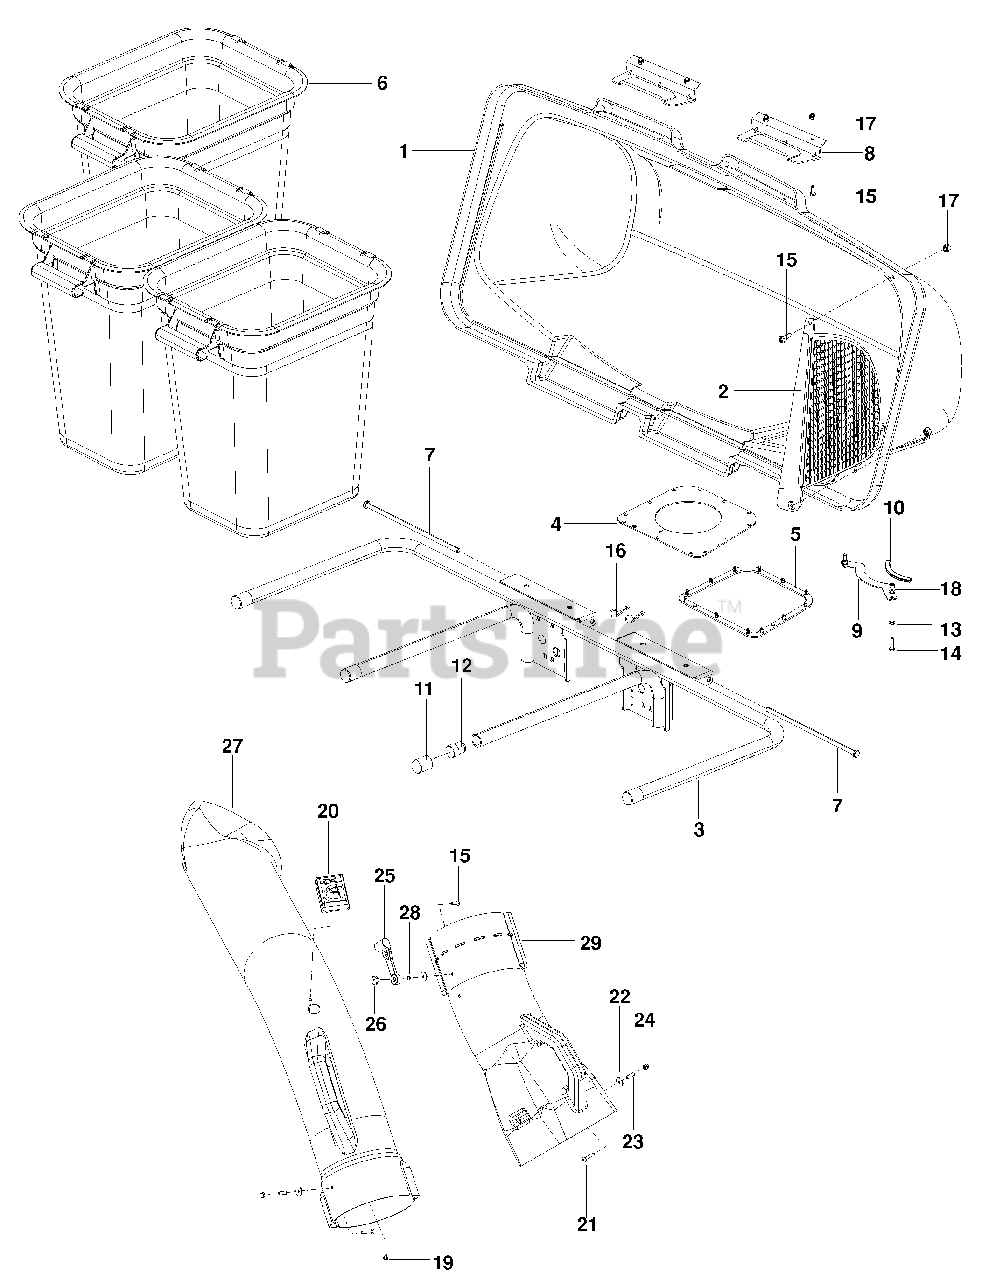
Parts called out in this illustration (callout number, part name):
2	Screen, Cover
3	Frame, Bagger
4	Seal, Cover
5	Gasket, Cover
6	Container, Soft Bag
7	Pin, Hinge
8	Handle, Bagger Cover
9	Support, Hose
10	Flex Trim, Black
11	Plug, Tubing End
12	Plug Spacer
13	Washer 5/16 Sae Flat
14	Hcs 5/16-18 X 11/4
15	Screw #10-24 X 5/8
17	Nut #10-24 Crownlock
18	Nut 5/16-18 Hex Nyloc
19	Screw, Spec 10-14 X 1/2
20	Indicator, Bag Dump
21	Screw 10-24 X 11/8
22	Washer 3/16 X 3/4
23	Spacer, Split
24	Nut, Acorn 10-24
25	Latch, Hood
26	Weld Nut, Plated
27	Chute, Upper
28	Washer 3/16 Lock
29	Chute, Middle
